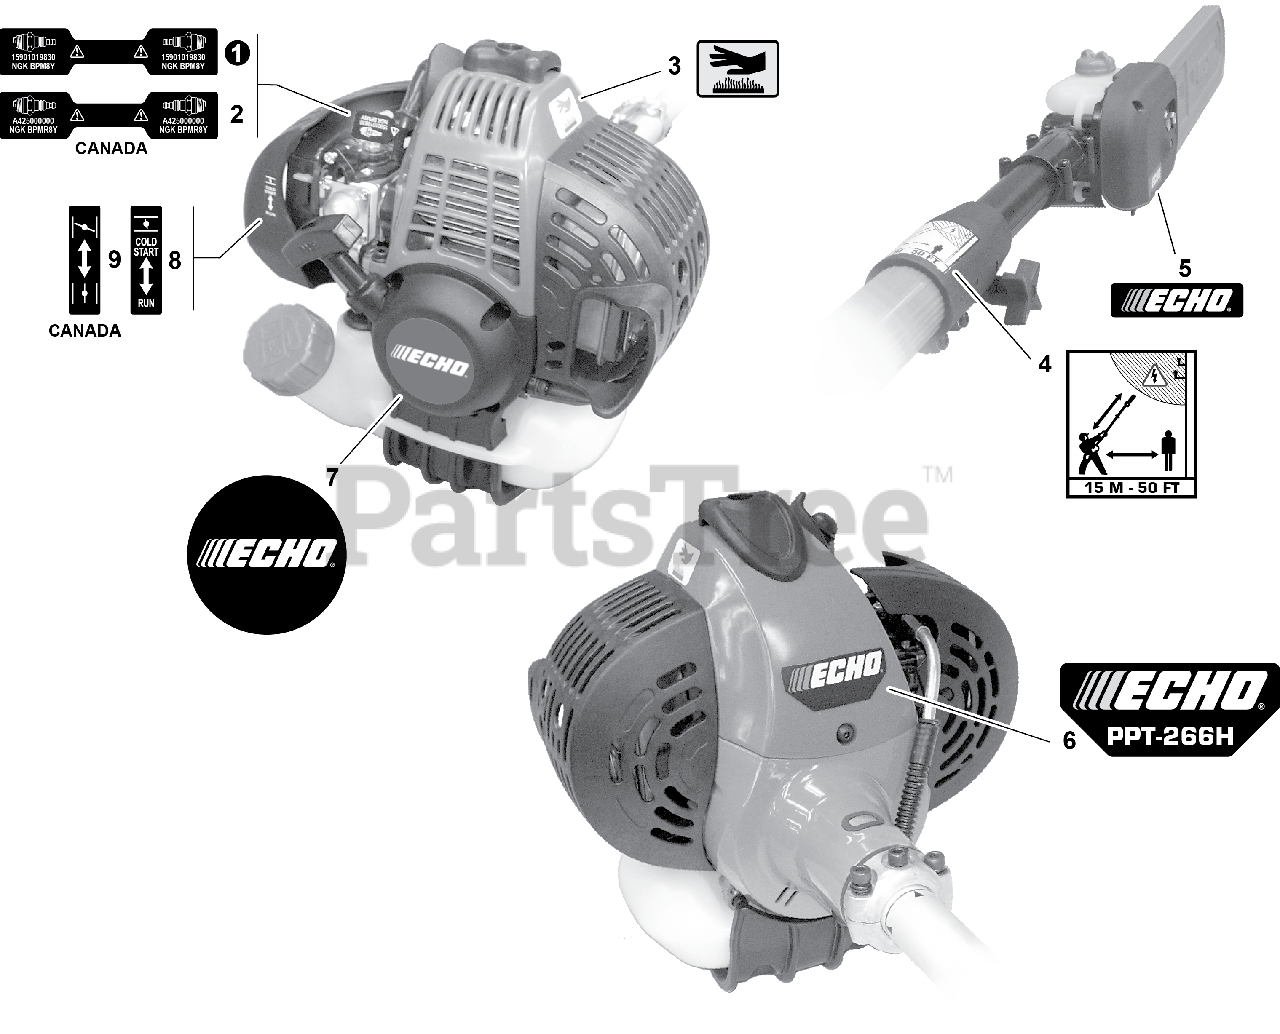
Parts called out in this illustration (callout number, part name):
1	LABEL, SPARK PLUG - BPM8Y
2	LABEL, SPARK PLUG - BPMR8Y
3	LABEL, CAUTION - HOT
4	LABEL, CAUTION
5	LABEL, ECHO
6	LABEL - MODEL PPT-266H
7	LABEL, ECHO
8	LABEL, CHOKE
9	LABEL, CHOKE
